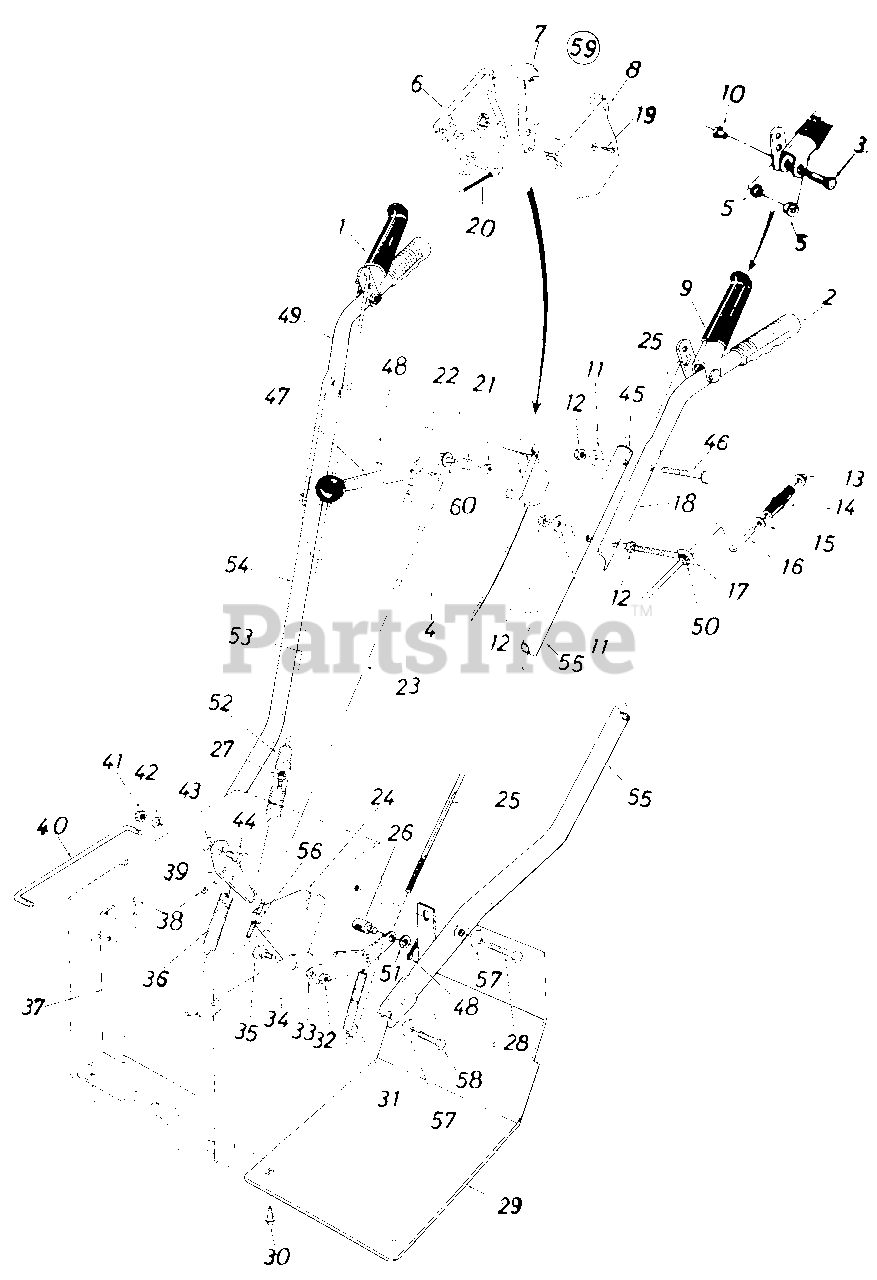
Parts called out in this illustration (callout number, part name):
1	Clutch Grip Ass'y. - R.H.
2	Grip
3	Shoulder Bolt .374 Dia. x 1.53" Lg.
4	Handle Panel Ass'y.
5	Hex Flange Plastic Bearing .380" I.D.
9	Clutch Grip Ass'y. - L.H.
10	Shoulder Nut 1/4-20 Thd.
11	Bell-Wash. .34" I.D. x .88" O.D.
12	Hex Nut 5/16-18 Thd.
13	Push Nut 3/8" Rod
14	Knob 3/8" Rod
15	Fl-Wash, .40" I.D. x .62" O.D.
16	Chute Crank Ass'y.
17	Eye Bolt 5/16-18 x 5.0" Lg.
18	Upper Handle - L.H.
20	Throttle Control Wire
21	Hex Ins. Jam L-Nut 3/8-16 Thd.
22	Compression Spring .50" O.D. x .88" Lg.
23	Shifting Rod 5/16" x 32.50" Lg.
24	Shifting Linkage Bracket
25	Lockout Rod .214" Dia. x 36.0" Lg.
26	Adjustment Ferrule 1/4-20
27	Hex Ins. L-Nut 1/4-20 Thd.
28	Hex Bolt 3/8-16 x 2.00" Lg.
29	Frame Cover
30	Hex Wash. Self-Tap Scr. 1/4-20 x .50" Lg.
31	Extension Spring .38" O.D. x 3.25" Lg.
32	Hex Jam Nut 3/8-16 Thd.
33	L-Wash. 3/8" I.D.
34	Auger Clutch Bracket Ass'y.
35	Shld. Bolt .625" Dia. x .170
36	Extension Spring .75" O.D. x 4.31" Lg.
37	Drive Pulley Support Brkt. Ass'y.
38	Cotter Pin 3/32" Dia. x .75" Lg.
39	Drive Clutch Bracket
40	Drive Clutch Rod
41	Hex Jam Nut 3/8-16 Thd.
42	L-Wash. 3/8" I.D.
43	Fl-Wash. .34" I.D. x .75" O.D.
44	Shld. Bolt .625" Dia. x .170
45	Plastic Plug
46	Carriage Bolt 5/16-18 x 2.0" Lg.
47	Shift Handle Ass'y.
48	Int. Cotter Pin 5/16" Dia.
49	Upper Handle - R.H.
50	Grommet
51	Fl-Wash. .28" I.D. x .62" O.D.
52	Extension Spring .75" O.D. x 5.00" Lg.
53	Lockout Rod .214" Dia. x 32" Lg.
54	Lower Handle - R.H.
55	Lower Handle - L.H.
56	Adjustment Ferrule
57	Bell-Wash. .40" I.D. x .88" O.D.
58	Hex Wash. Self-Tap Scr. 3/8-16 x .75" Lg.
59	Throttle Control Box Ass'y.
60	Bell-Wash. .40" I.D. x .88" O.D.
